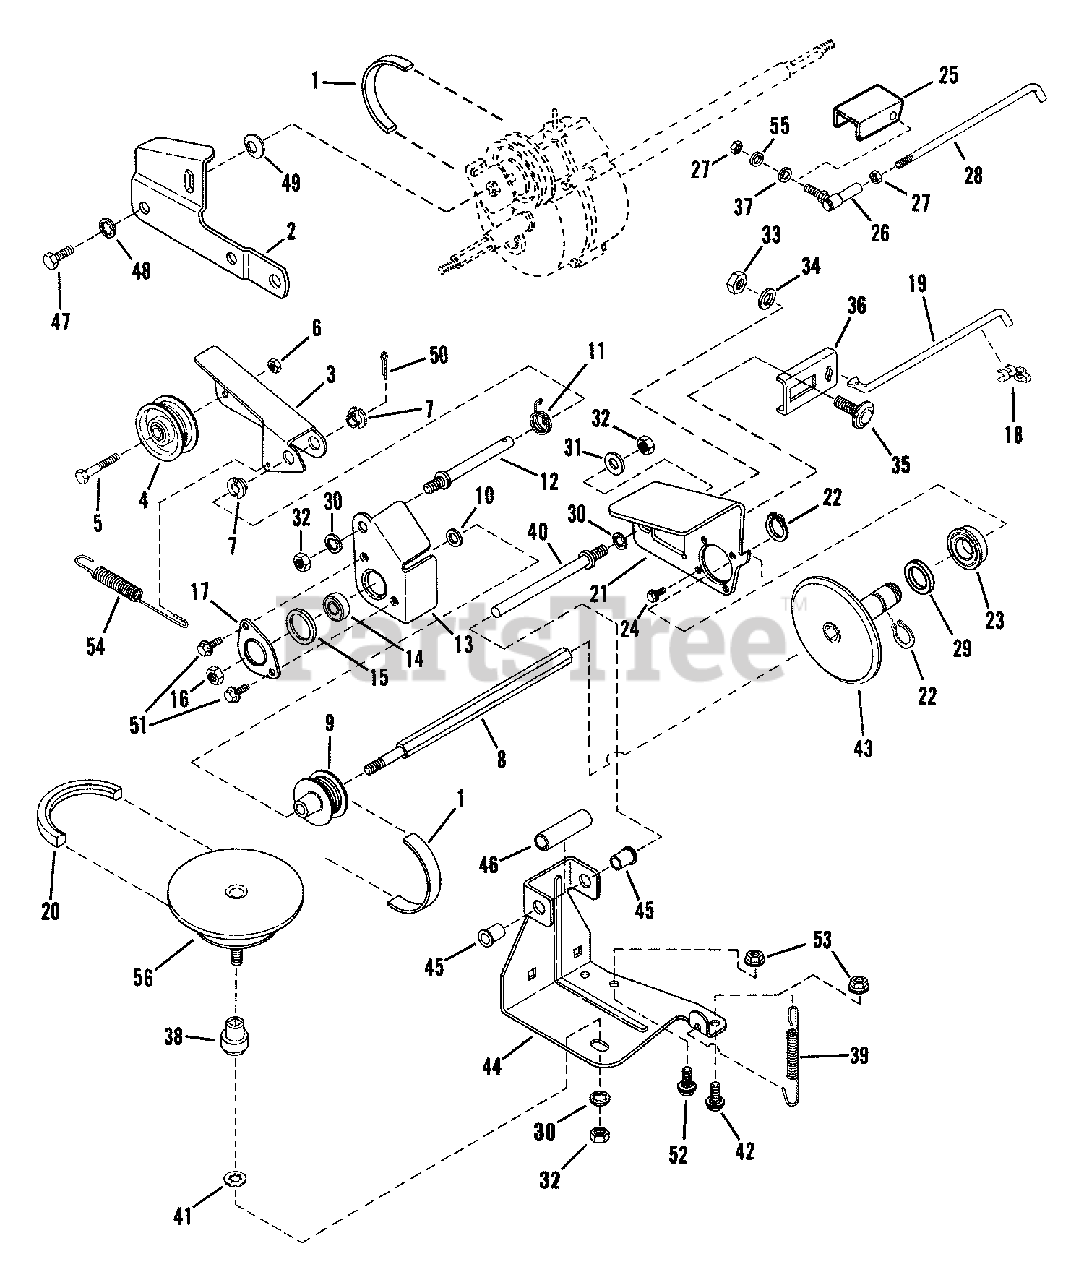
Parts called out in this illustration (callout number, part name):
1	BELT, Poly-Vee
2	LINK, Differential
3	ARM, Clutch Idler
4	PULLEY, Idler
5	SCREW, 1/4-28 x 1-3/8" Hex Head Cap GR5
6	NUT, 1/4-28 Hex Top Lock
7	BUSHING, 3/8" Plastic
8	SHAFT, Hex Drive
9	PULLEY, Poly-V, 2" O.D.
10	WASHER, 3/8" Flat
11	SPRING, Torsion
12	STUD, Idler (3/8-24 thread)
13	HOLDER, Bearing (Inner Half)
14	BEARING, Ball, .38 I.D. Spherical O.D.
15	O-RING
16	NUT, 3/8-24 Hex Center Lock GR5 or B
17	HOLDER, Bearing (Outer Half)
18	CLIP, Transfer Rod 1/4"
19	ROD, Transfer
20	BELT, Engine Drive 3L (Stretch)
21	PLATE, Thrust
22	RING, 5/8" External Retaining
23	BALL BEARING, 3/4" I.D.
24	SCREW, #10-32 x 1/4" Self-Tap Machine
25	SHIELD, Hex Shaft
26	BALL JOINT, 1/4-28
27	NUT, 1/4-28 Hex GR5
28	LINK, Transfer
29	WASHER, 3/4" Shim
30	WASHER, 3/8" Internal Tooth Lock
31	WASHER, 3/8" Flat
32	NUT, 3/8-24 Hex, GR B
33	NUT, 5/16-18 Hex GR5 or B
34	WASHER, 5/16" Split Lock
35	BOLT, 5/16-18 x 3/4" Short Neck Carriage GR5
36	CONNECTOR, Transfer Rod
37	WASHER, Flat 1/4" (European Models Only)
38	BUSHING
39	SPRING, Wheel Drive
40	GUIDE, Thrust Plate (3/8-24 thread)
41	RETAINER, 3/8" Bolt
42	BOLT, 5/16-18 x 5/8" Short Neck Carriage GR5
43	DISC, Driven (Cantilever)
44	BRACKET, Deck
45	BUSHING, Flange
46	SPACER
47	SCREW, 5/16-18 x 1/2" Hex Head Cap, GR5
48	WASHER, 5/16" Internal Tooth Lock
49	WASHER, Spring
50	PIN, 3/32 x 1/2" Cotter
51	SCREW, 1/4-20 x 1/2" Hex Washer Self-Tap
52	BOLT, 5/16-18 x 1/2" Short Neck Carriage GR5
53	NUT, 5/16-18 Hex Flange Lock, GR5
54	SPRING, Clutch
55	WASHER, 1/4" Internal Tooth Lock
56	KIT, Drive Disc Assembly
